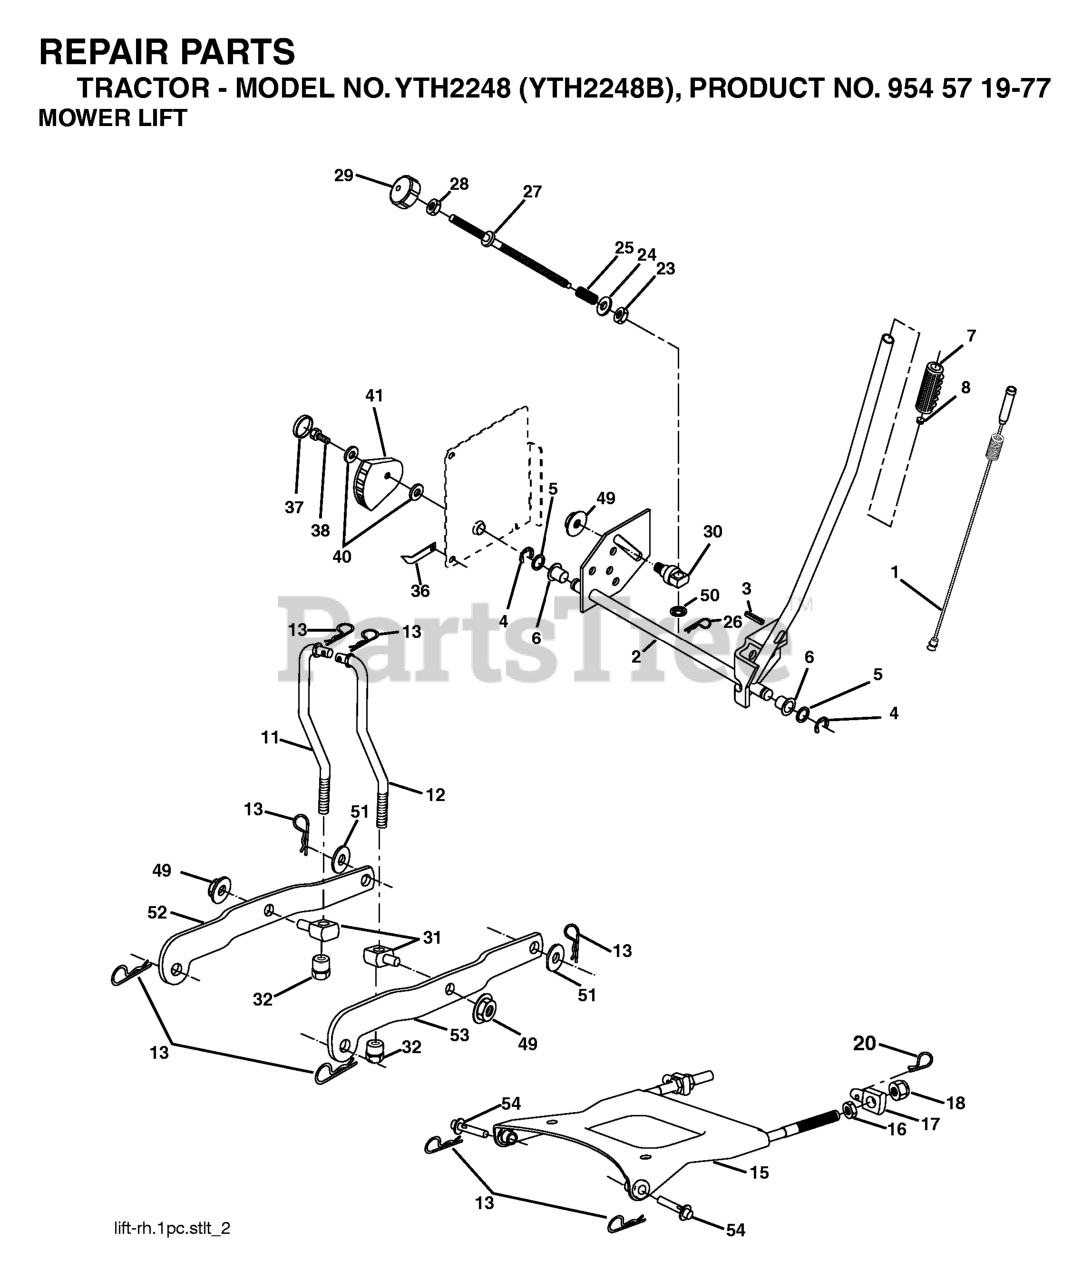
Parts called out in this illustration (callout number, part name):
1	WIRE ASM INNER W/ PLUNGER LT
2	SHAFT ASM R HANDLE
3	PIN GROOVE.
4	RETAINING RING LT
6	BEARING.NYLON
7	GRIP HANDLE
8	PLUNGER BUT KIT
11	LIFT LINK LH
12	LIFT LINK RH
13	RETAINER-SPRNG RB
15	PLATE ASM SUSP FRONT
16	NUT.HEX.JAM.1/2-13
18	NUT.LK.W/WSH.1/2.
20	SPRING RETAINER
25	SPRING**
26	RETAINER CLIP
27	ROD ADJ LIFT
28	NUT
29	KNOB INF 3/8-16
32	NUT, LIFT LINK 7/16-20
36	POINTER, HEIGHT INDICATOR(2 2)
38	SCREW 5/16-18X1
41	IND. HEIGHT STLT
49	NUT
50	NUT PUSH M
51	Washer 1 17/32 X 7/8 X 16 Ga
52	ARM SUSP. REAR LH
53	ARM SUSP REAR RH
54	PIN.FLANGE
